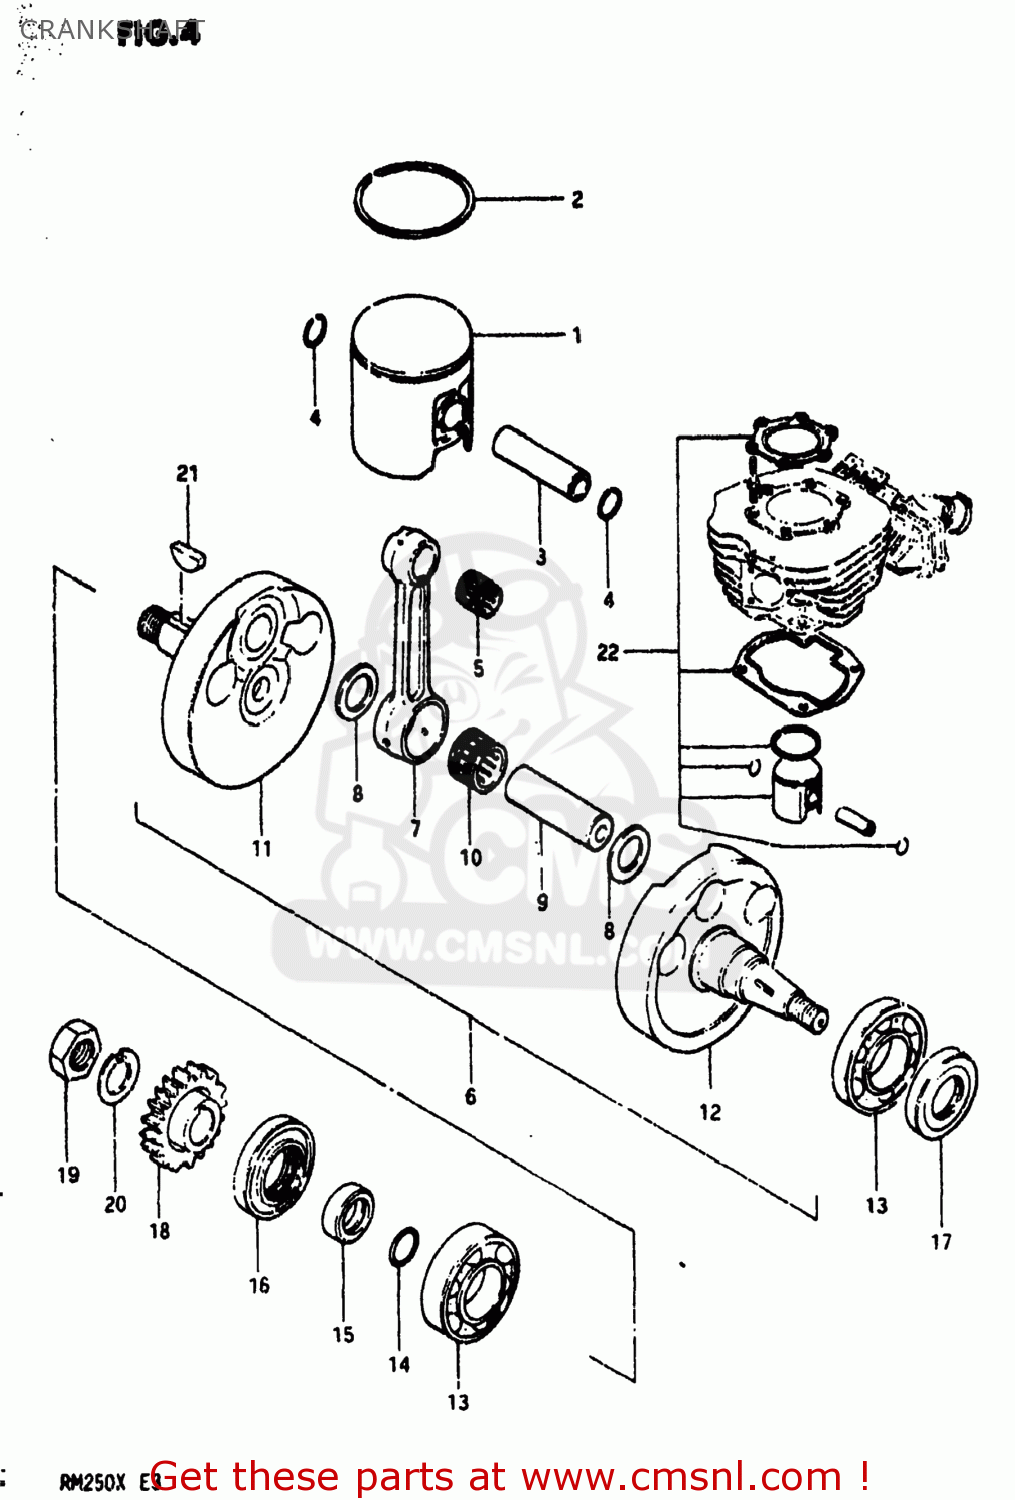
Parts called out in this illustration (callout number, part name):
1	PISTON (67.00MM)
2	RING,PISTON
3	PIN,PISTON (18MM)
4	CIRCLIP
5	BEARING(18X22X22)
6	CRANKSHAFT ASSEMBLY
7	ROD,CONNECTING
8	WASHER(24X29X1.5)
9	PIN,CRANK
10	BEARING
11	CRANKSHAFT
12	CRANKSHAFT,LEFT
13	BEARING
14	O RING(D:2.4,ID:21.8)
15	SPACER,PRIMARY DRIVE GEAR
16	SEAL,OIL(36X52X8)
17	SEAL,OIL(19.6X37X8)
18	GEAR,PRIMARY DRIVE
19	NUT
20	WASHER
21	KEY
22	PISTON SET
